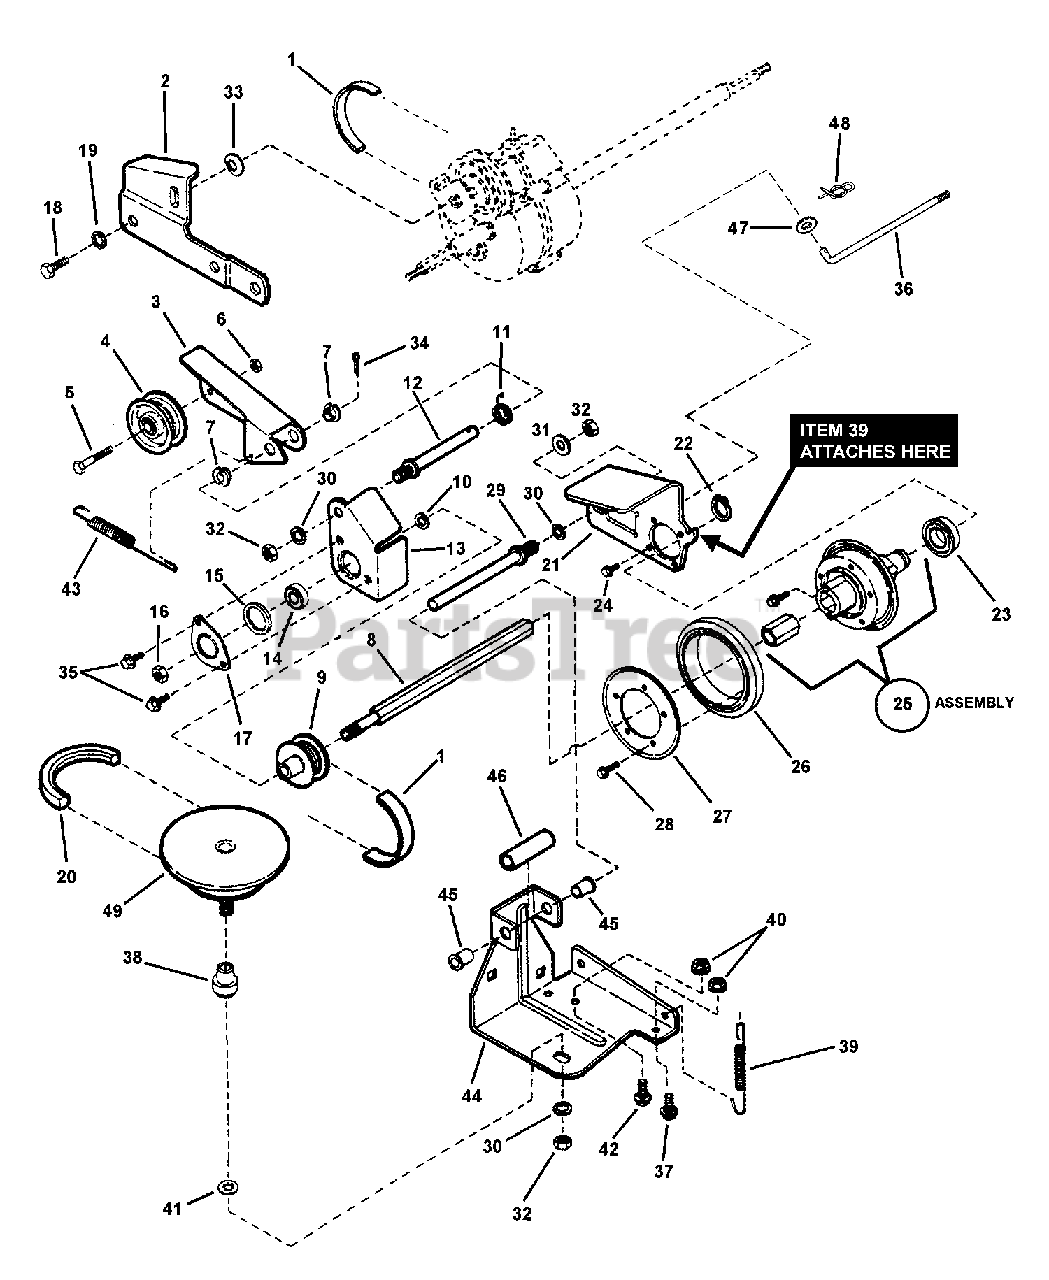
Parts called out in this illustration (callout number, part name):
1	BELT, Poly-V
2	LINK, Differential
3	ASSEMBLY, Clutch Idler (Incl. items 3 thru 7)
3	ARM, Clutch Idler
4	PULLEY, Idler
5	SCREW, 1/4-28 x 1-3/8" Hex Head Cap, GR 5
6	NUT, 1/4-28 Hex Top Lock
7	BUSHING, 3/8" I.D. Nylon
8	* SHAFT, Hex Drive
9	PULLEY, Poly-V (2.00" O. D.)
10	WASHER, 3/8" Flat
11	SPRING, Idler- Torsion
12	STUD, Idler (3/8-24 thread)
13	HOLDER, Bearing (Inner Half)
14	BALL BEARING, Spherical O.D., .38 I.D.
15	O-RING
16	NUT, 3/8-24 Hex Center Lock, GR 5
17	HOLDER, Bearing (Outer Half)
18	SCREW, 5/16-18 x 1/2" Hex Head Cap, GR 5
19	WASHER, 5/16" Internal Tooth Lock
20	BELT, Engine Drive (Stretch)
21	THRUST PLATE, Short
22	RETAINING RING, .625 External
23	BALL BEARING, 3/4" Bore- Commercial
24	SCREW, #10-32 x 1/4" Self-Tap Machine
25	ASSEMBLY, Hub (Includes 11108 Bushing & 90913 Screws)
26	RING, Driven (Rubber Disc)
27	PLATE, Ring Retaining
28	SCREW, #10-24 x 1/2" Hex Washer Self-Tap (Torx)
29	GUIDE, Thrust Plate (3/8-24 thread)
30	WASHER, 3/8" Internal Tooth Lock
31	WASHER, 3/8" Flat
32	NUT, 3/8-24 Hex
33	WASHER, 44 x .78 x .025 Curved
34	COTTER PIN, 3/32 x 1/2"
35	SCREW, 1/4-20 x 1/2" Hex Flange Self-Tap
36	LINK, Transfer (1/4-28 thread)
37	BOLT, 5/16-18 x 5/8" Short Neck Carriage GR 5
38	BUSHING, Powdered Metal
39	SPRING, Wheel Drive
40	NUT, 5/16-18 Hex Flange Lock GR 5
41	RETAINER, 5/16" Bolt
42	BOLT, 5/16-18 x 1/2", Short Neck Carriage, GR 5
43	SPRING, Clutch- 21S
44	ASSEMBLY, Deck Bracket (Incl. items 44 thru 46)
44	BRACKET, Deck, P21S
45	BUSHING, Flange
46	SPACER, .500 x .65 x 1.75
47	WASHER, .28 x .63 x .06 Flat
48	COTTER PIN, .06 x .50
49	ASSEMBLY, Steel Drive Disc
